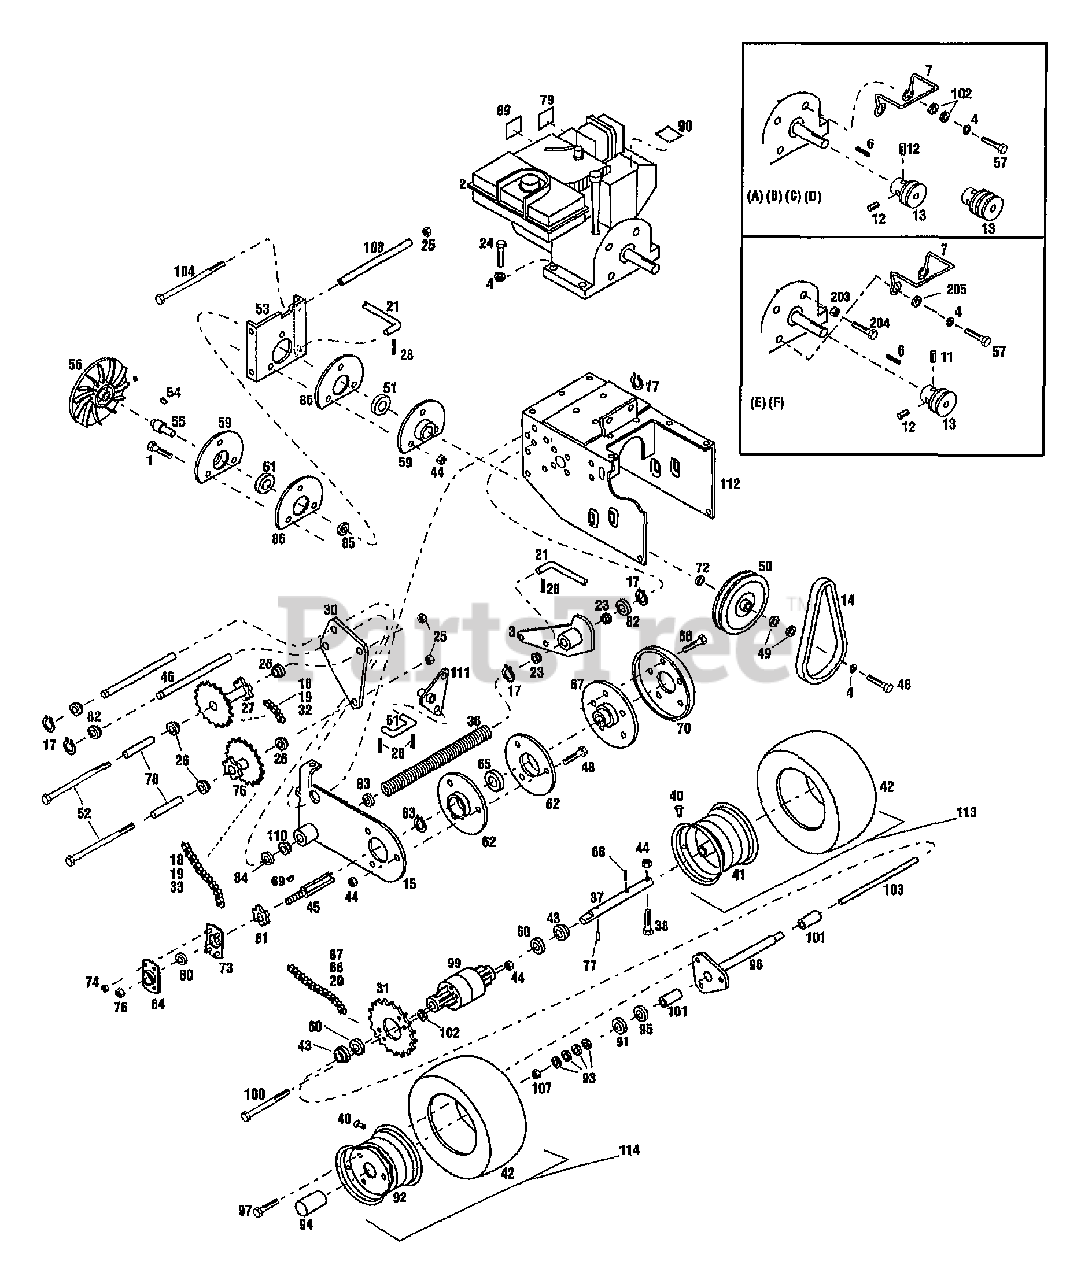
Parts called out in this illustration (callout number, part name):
1	SCR-HH 5/16-18X1.0 G5 ZP
2	ENGINE, TECUMSEH 8HP, MODEL HMSK 80
2	ENGINE, TECUMSEH 10HP, MODEL HMSK 100
3	ASSM-CONTROL ARM
4	WASHER-LK .312 ZP
6	KEY-.25 SQ X 1.25
7	GUIDE-BELT
11	SCR-SQ HD SET
12	SCR-SET SQ 5/16-18X5/8
13	SHEAVE-ENGINE
13	PULLEY-ENGINE
14	BELT-V 32"
15	SUPT-DRIVE W/BEARING
17	RING-RETAIN .625 ID
18	LINK-OFFSET (HALF LINK)
19	LINK-CONNECTOR #41 CHAIN
20	CHAIN-DRIVE
21	LINK-CONTROL
23	BUSHING-FLANGE
24	SCR-HH 5/16-18X1.5 G5 ZP
25	NUT-HFLK 3/8-16 ZP
26	BEARING-FLANGE
27	ASSM-SPROCKET 9T/17T
28	PIN-COTTER .09X.75 ZP
30	PLATE-SUPPORT
31	SPROCKET-30T
32	CHAIN-DRIVE
33	CHAIN-DRIVE
36	SPRING-COMPRESSION
37	SHAFT-AXLE
38	SCR-HH 5/16-18X1.75 G5ZP
40	STEM-VALVE
41	DISC-WHEEL
42	TIRE-4.80 X 8
43	BUSHING-.875 FLNG
44	NUT-TOP/LK 5/16-18 ZP
45	SHAFT-HEX
46	SUPPORT-SHAFT
48	SCR-HHC 5/16-18X.75 GR 5 ZP
49	WASHER-1.25X.343X.059
50	SHEAVE-DRIVE WHEEL
51	BEARING-BALL
52	SCR-HHC 3/8-16X3.25
53	ASSM-DRIVE DISC WELD
54	KEY-WOODRUFF
55	SPINDLE
56	PLATE-DRIVE
57	SCR-HH 5/16-24X1.00 G5ZP
59	RETAIN-BEARING
60	WASHER-.875
61	LINK-CONTROL SC
62	RETAINER-BEARING
63	RING-SNAP
64	BEARING-FLANGE
65	BEARING-THRUST
66	SCR-HFLK 5/16-18X.50 ZP
67	HUB-FRICTION DISC
68	PIN-DRIVE
69	KEY-WOODRUFF 1/8 X 5/8
70	DISC-FRICTION
72	WASHER-1.12X.759X.0329
73	ASSM-BEARING FLANGE
74	NUT-H/LK M10-24 NYLOCK
75	ASSM-SPROCKET 9T/30T
77	PIN-DRIVE .187X.9
78	SPACER-.62X.39X2.625
79	DECAL-CHOKE
80	BEARING-BALL
81	SPROCKET-9T
82	BUSHING-.68X.62X.15 FLNG
83	WASHER-1.0X.64X.029
84	WASHER-1.305X.649X.098 ZP
85	SPACER-1.0X.766X.413
86	RETAINER-BEARING
87	LINK-CONNECTOR
88	LINK-OFFSET
89	DECAL-PRIMER @ DEPL
90	DECAL-WARN.HOT SURFACES
91	WASHER-D HOLE
92	DISC-WHEEL
93	DISC-SPRING
94	CAP-DUST
95	DISC-FRICTION
96	TUBE-AXLE W/FLANGE
97	BOLT-LUG SC
99	ASSM-DIFFERENTIAL
100	BOLT-HH 5/16-18X4 1/2
101	BUSHING-NYLON
102	SPACER-.625X.343X.5
103	SHAFT-AXLE
104	SCR-HH 3/8-16X8.5 G5ZP
107	NUT-HEX JAM 1/2-13
108	SPACER-.5X.384X7.375
110	BEARING-FLANGE
111	ARM-CONTROL SPEED
112	ASSM-FRAME
113	ASSM-WHEEL&TIRE LH
114	ASSM-WHEEL&TIRE RH
203	NUT-HEX 5/16-24
204	SCR-HHC 5/16-24X4.0 GR5
205	WASHER-FLAT 5/16 SAE
